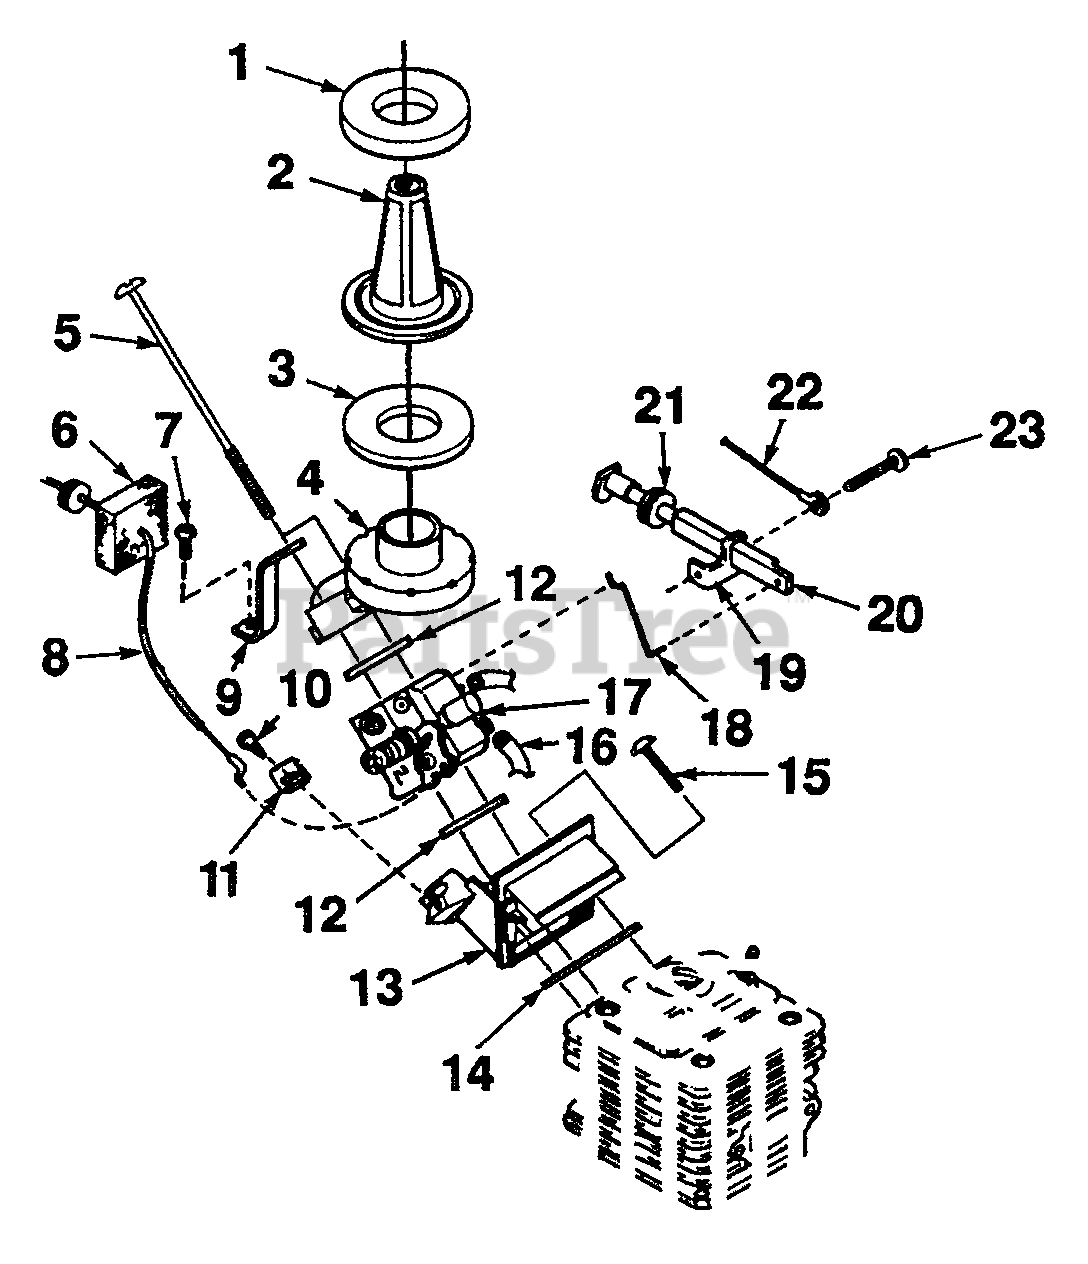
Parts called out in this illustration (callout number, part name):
1	GASKET-Foam (1/4")
2	FILTER-Screen
3	GASKET-Foam
4	ADAPTOR-Intake
5	SCREW-Truss Hd. (8-16 X 3 1/4")
6	PAD-Foam
7	SCREW-Torx (10-24 X 1/2")
8	CABLE-Throttle
9	BRACKET-Air Intake
10	SCREW-Thread Form. (6-19 X 1/2")
11	BRACKET-Cable End
12	GASKET-Adaptor
13	ADAPTOR-Intake
14	GASKET-Carburetor
15	SCREW-Pan Hd. (10-24 X 1")
16	TUBING,Pulse line (4 3/4")
17	CARBURETOR-Walbro
18	CHOKE LINK & RETAINER
19	BRACKET-Cable
20	ROD-Choke
21	GROMMET
22	GROUND WIRE
23	SCREW-Truss Hd. (10-24 X 1 1/4")
